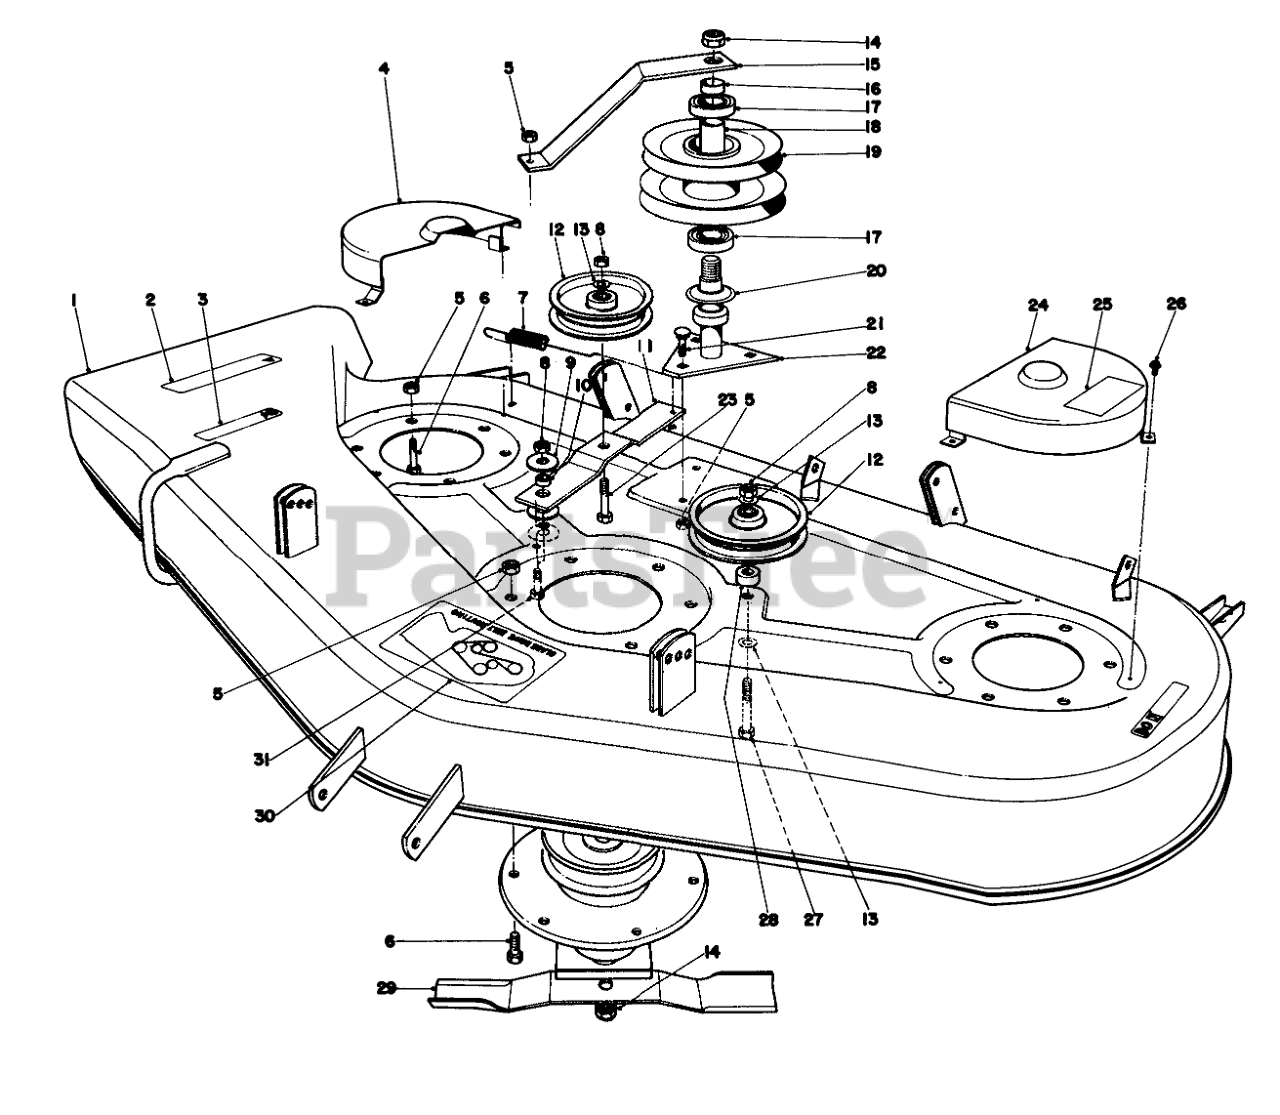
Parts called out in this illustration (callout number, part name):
2	CAUTION DECAL
3	DECAL-NO STEP
4	RH BELT COVER WA B
5	NUT-LOCK, CONE
6	SCREW-HH
7	EXT SPRING O
8	NUT-LOCK, CONE
9	WASHER
10	IDLER BRKT SPACER
11	Idler Pulley Bracket
12	PULLEY-IDLER
13	WASHER-FLAT
14	NUT-LOCK, NI
15	Support Spindle
16	SPACER
17	BEARING
18	SPACER
19	Pulley & Bearing Assembly
20	DUST COVER
21	BOLT-CARR
22	SHAFT SADDLE ASM
23	SCREW-HH
24	LH BELT COVER WA B
25	Decal Wheel Adjustment
26	SCREW-HWHTF
27	SCREW-HH
28	SPACER O
29	Blade
30	Decal Belt Routing
31	SCREW-HH
